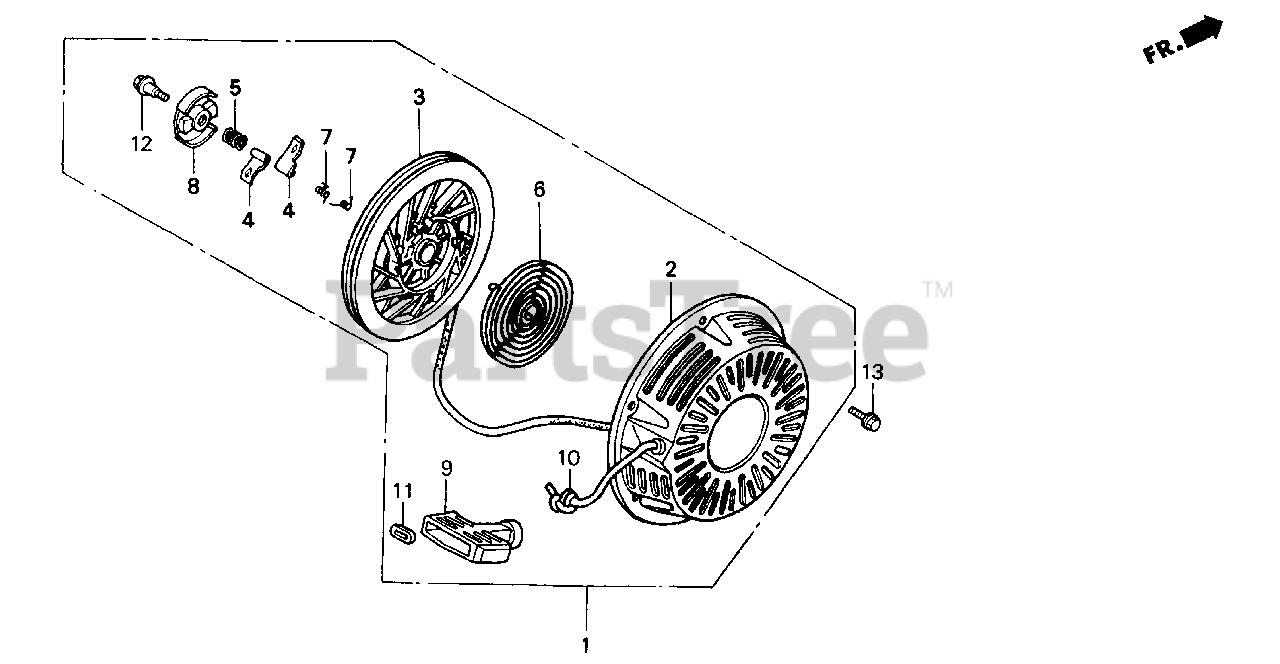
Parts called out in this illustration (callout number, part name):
1	STARTER ASSY., RECOIL *R8* (BRIGHT RED)
2	CASE, RECOIL STARTER *R8* (BRIGHT RED)
3	PULLEY, RECOIL STARTER
4	RATCHET, STARTER
5	SPRING, FRICTION
6	SPRING, STARTER RETURN
7	SPRING, RATCHET
8	RETAINER, SPRING
9	GRIP, STARTER
10	ROPE, RECOIL STARTER (N/A: USE P/N 08560-ZG921-11)
11	GRIP, REINFORCEMENT
12	SCREW, CENTER
13	BOLT, FLANGE (6X10)
